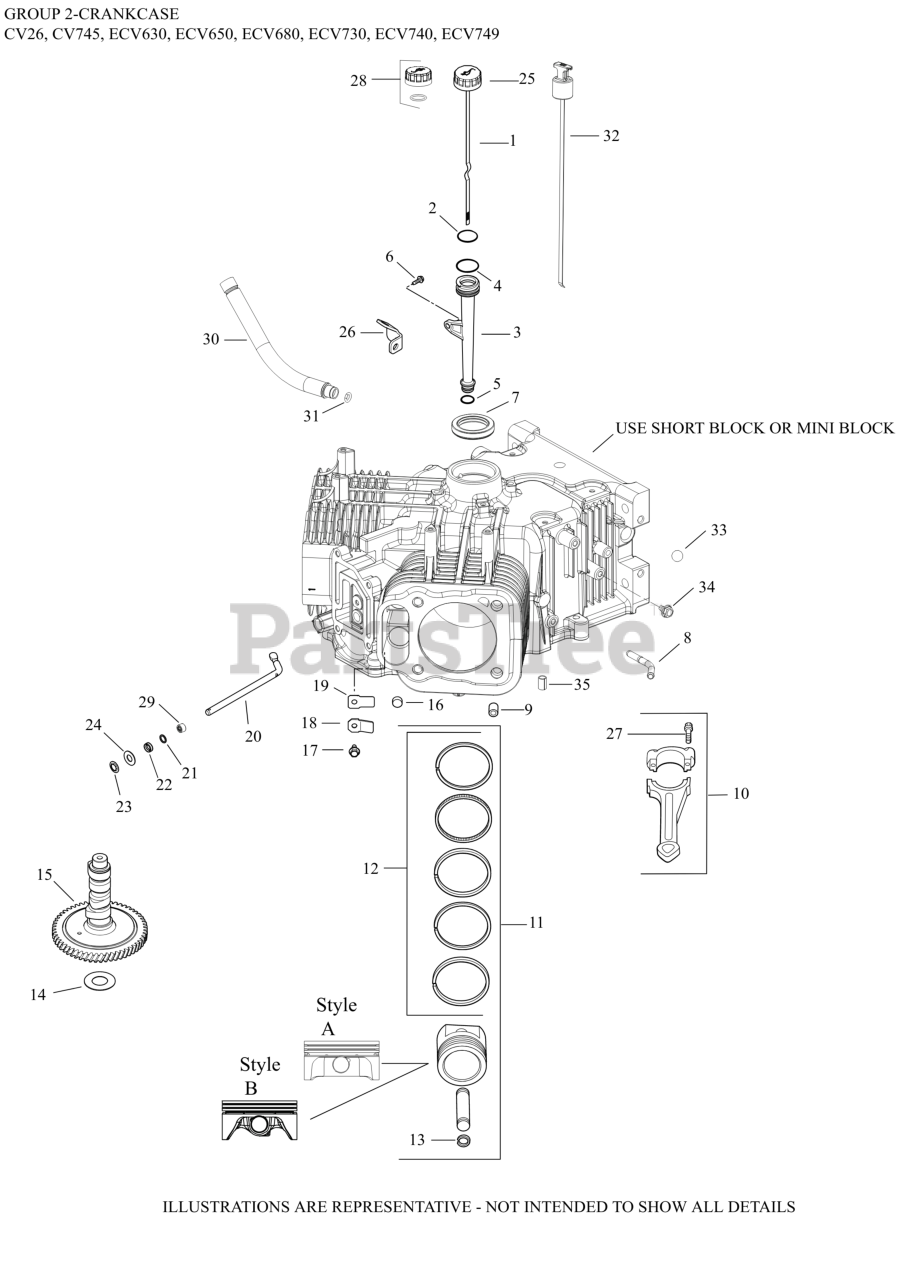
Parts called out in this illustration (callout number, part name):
1	DIPSTICK, ASSY
2	O-RING, DIPSTICK
3	TUBE ASSEMBLY
4	O-RING, UPPER OIL FILL TUBE
5	O-RING, LOWER OIL FILL TUBE
6	SCREW, FLG THD FRM M5X0.8X13
7	SEAL, OIL (HELIX LIP)
9	PIN, LOCATING
10	ROD, ASSEMBLY CONNECTING
11	KIT,PSTN/RNG STYLE A(STD)(#2587406S)
11	KIT,PSTN/RNG STYLE A(.08)
11	KIT,PSTN/RNG STYLE A(.25)USE 2587411-S
11	KIT,PSTN/RNG STYLE A(.50)(#2587404S)
11	KIT,PSTN/RNG STYLE B(STD)
11	KIT,PSTN/RNG STYLE B(.08)
11	KIT,PSTN/RNG STYLE B(.25)
11	KIT,PSTN/RNG STYLE B(.50)
12	RING DISC USE PISTON ASSY PER SPEC
12	RING SET(.08)STYLE A-1.5mm Tp RING THICK
12	RING SET(.25)STYLE A-1.5mm Tp RING THICK
12	RING SET(.50)STYLE A-1.5mm Tp-(#DSC)
12	RING SET(STD)STYLE B-1.2mm Tp RING THICK
12	RING SET(.08)STYLE B-1.2mm RING THICK
12	RING SET(.25)STYLE B-1.2mm Tp RING THICK
12	RING SET(.50)STYLE B-1.2mm Tp RING THICK
13	RETAINER, PISTON PIN
15	KIT, CAMSHAFT
16	PLUG, CUP
17	SCREW, FLG THD FRM M5X.8X10
18	RETAINER, BREATHER REED
19	REED, BREATHER-(#2440207S)
20	SHAFT, GOVERNOR CROSS
21	WASHER, FLAT 11/32"
22	SEAL, GOVERNOR CROSS SHAFT
23	RETAINER, RING
24	WASHER, FLAT 9 MM
25	KIT, OIL FILL CAP (YELLOW)
27	KIT, ROD BOLTS-(#25086677S)
